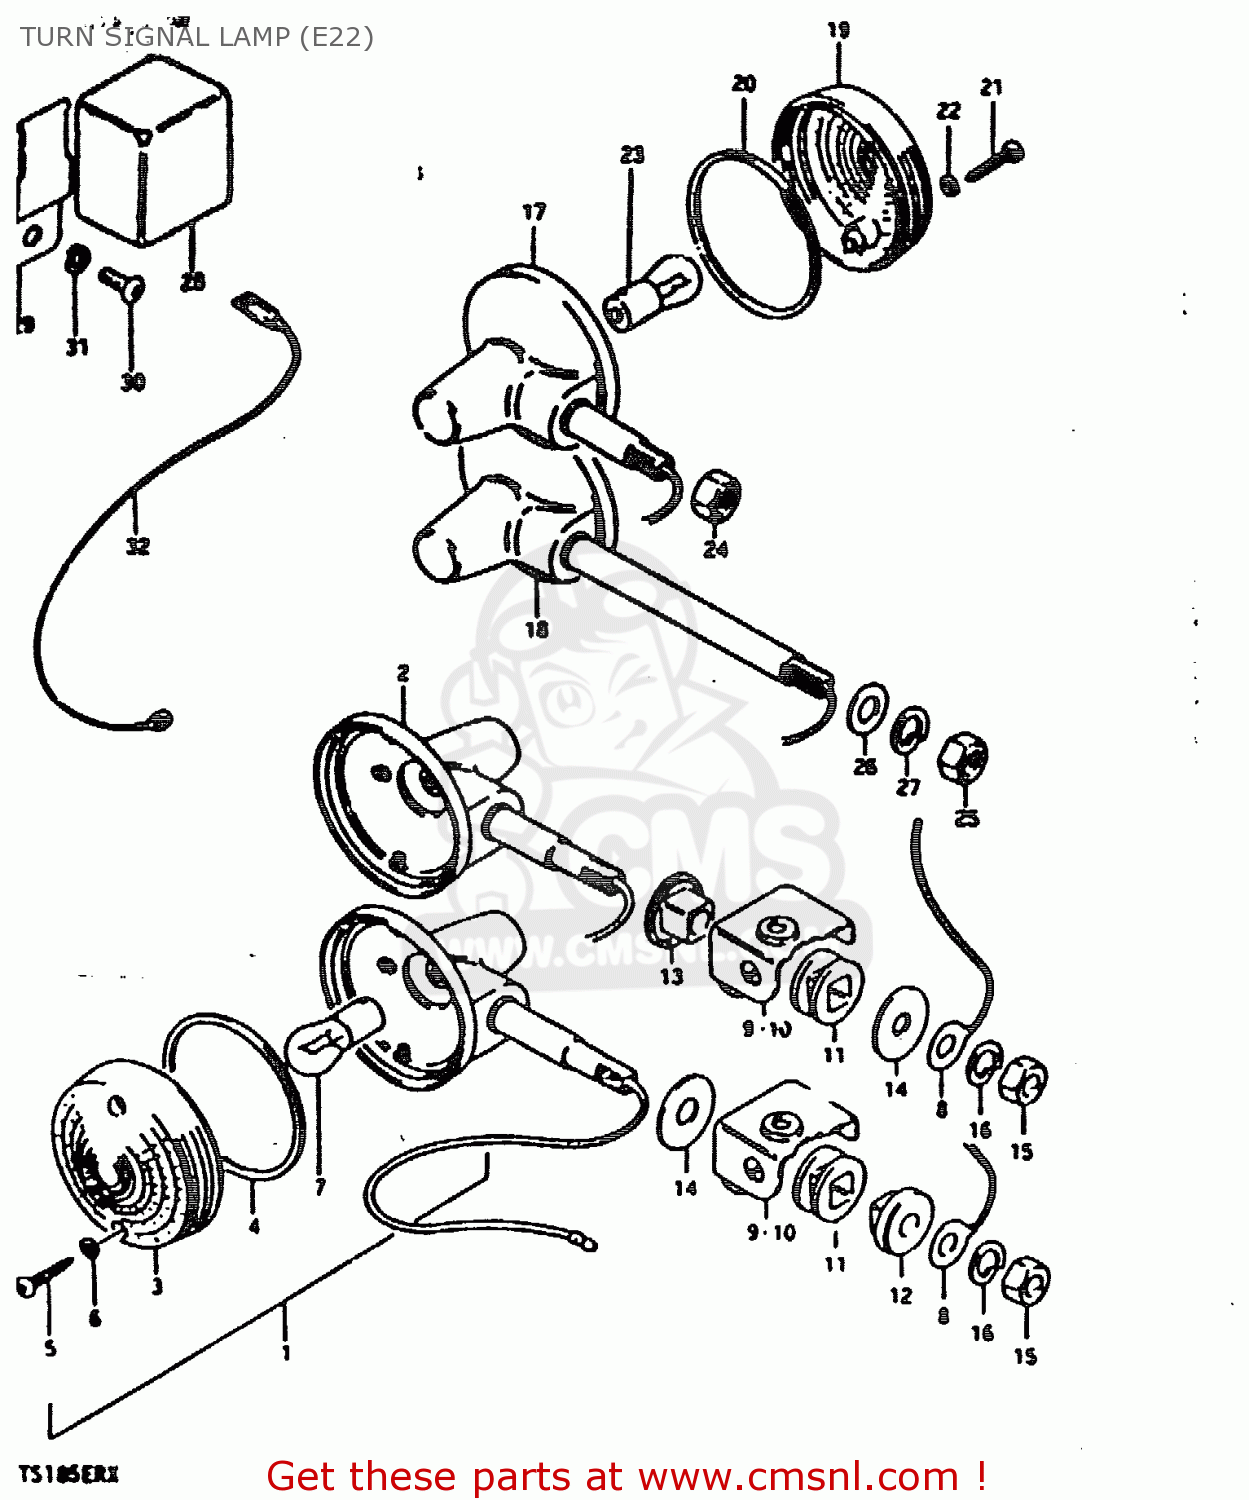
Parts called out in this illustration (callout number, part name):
1	LAMP, FRONT TURN SIGNAL
2	LAMP ASSY,FR TURN SIGNAL
3	LENS
4	GASKET (NAS)
5	SCREW
6	GASKET (NAS)
7	BULB (6V,21W)
8	LEAD WIRE,EARTH
9	BRACKET,TURNSIGNAL LAMP,R
10	BRACKET,TURNSIGNAL LAMP,L
11	CUSHION
12	SPACER,RR TURNSIGNAL LAMP
13	SPACER
14	WASHER (10.5X30X2.3)
15	NUT
16	LOCK WASHER
17	LAMP, REAR TURN SIGNAL
18	LAMP, REAR TURN SIGNAL
19	LENS
20	GASKET (NAS)
21	SCREW
22	GASKET (NAS)
23	BULB (6V,21W)
24	NUT
25	NUT
26	WASHER
27	LOCK WASHER
28	RELAY, TURN SIGNAL
29	BRACKET,TURN SIGNAL RELAY
30	SCREW 6X12
31	LOCK WASHER
32	LEAD WIRE, RELAY EARTH
